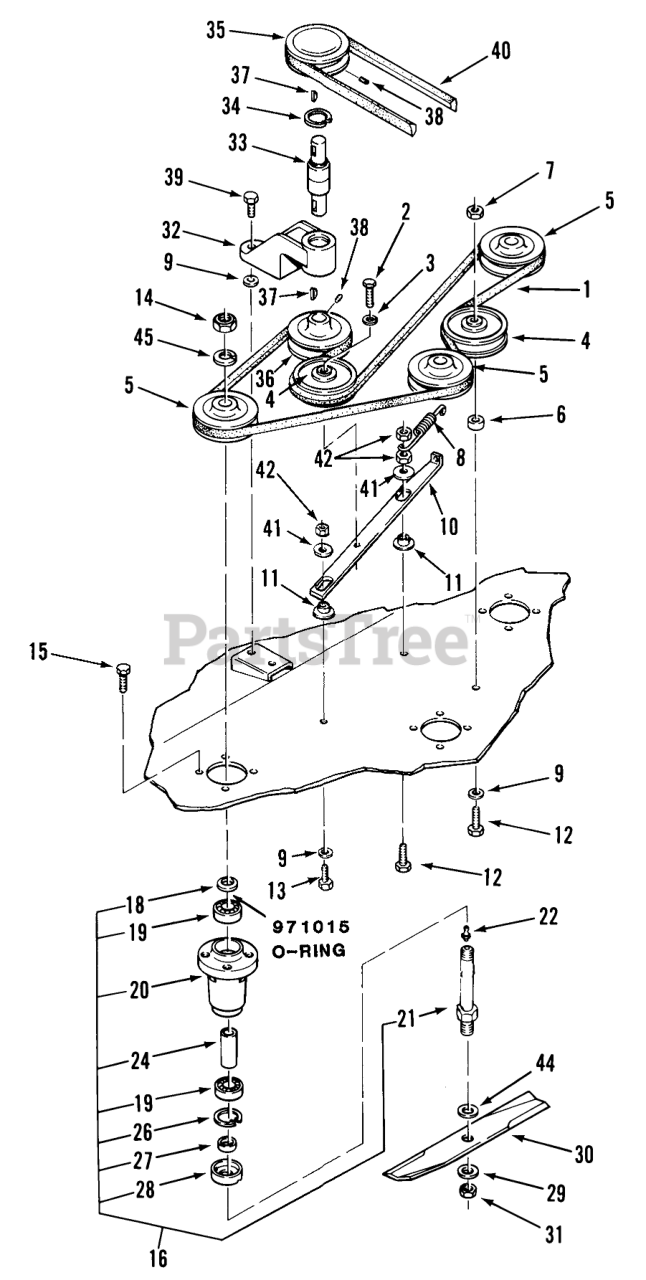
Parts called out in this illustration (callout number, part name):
1	BELT-V
2	BOLT HEX SPECIAL
3	LOCKWASHER
4	Idler Pulley
5	PULLEY
6	SPACER
7	Nut
8	SPRING-EXTENSION
9	WASHER
10	BAR-IDLER SUPPORT
11	SPACER-BUSHING
12	Bolt
13	Bolt
14	Nut
15	Bolt
16	ASSY 36" SPINDLE
18	Washer
19	BEARING-BALL
20	HOUSING-SPINDLE
21	Spindle Shaft
22	Zerk
24	Spacer
26	Ring-Snap
27	SPACER-BLADE
28	CUP-SPINDLE
29	SpeciaI Washer
30	S/A BLADE KIT
31	Nut
32	HOUSING DRIVE BRG R
33	BEARING-INT SHAFT
34	Snap Ring
35	PULLEY
36	PULLEY-SPLIT
37	KEY-WOODRUFF
38	Set Screw
39	Bolt
40	V-BELT
41	WASHER
42	NUT
44	Washer
45	Lockwasher
